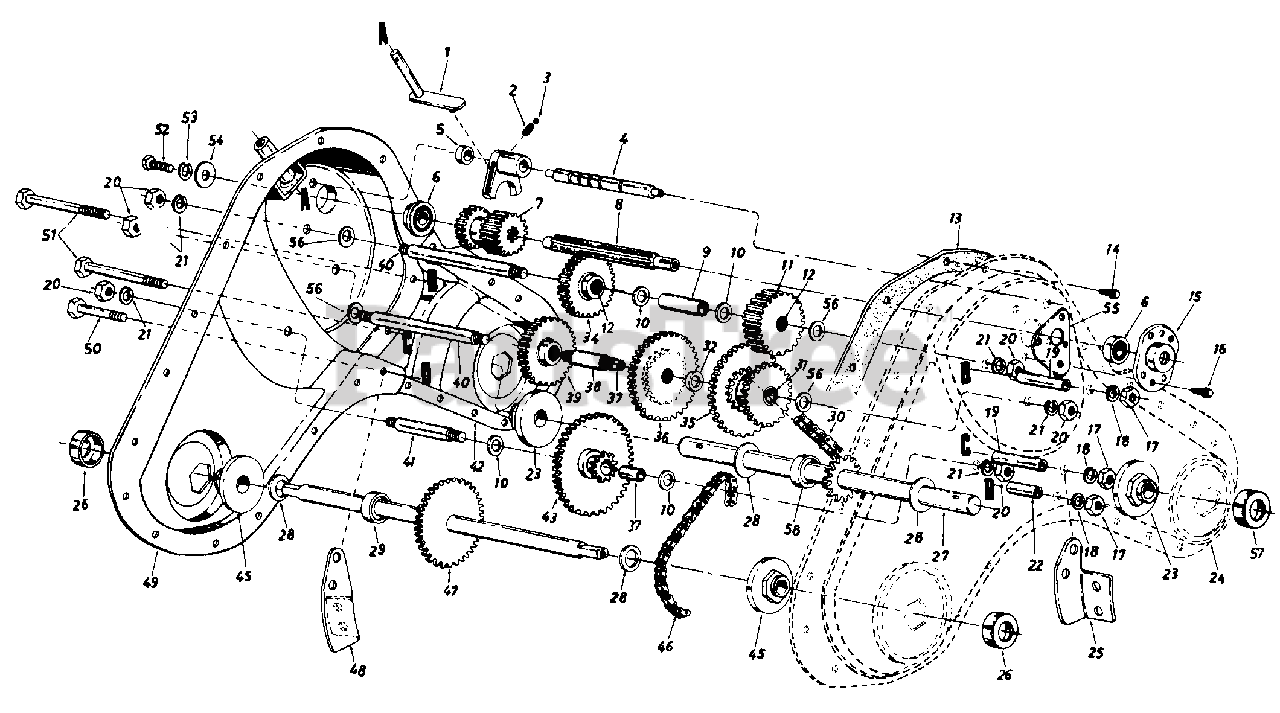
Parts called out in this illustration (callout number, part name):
1	Shifting Bracket Ass'y.
2	Compression Spring .50n Lg.
3	Ball Detent .250" Dia.
4	Detent Shaft 1/2" Dia.
5	Spacer .505" I.D. x.88" O.D.
6	Ball Brg. .62" I.D. x 1.38"
7	Spur Gear 16T
8	Input Spline Shaft 7/8
9	Spacer 657n I.D. x 2.85" Lg.
10	Fl-Wash. 640n I.D. x 1.24n
11	Spur Gear 30T 7/8" I.D. x 11/4 " O. D .
12	Needle Bearing 5/8n I.D.
13	Gasket-Trans. Hsg.
14	Hex Wash. S-Tap Scr. 1/4-20 x.50" Lg.
15	1-3/8" Dia. Bearing Housing
16	Hex TT-Tap Scr. 1/4-20 x .75"
17	Hex Nut 5/16-18 Thd.
18	L-Wash. 5/16" I.D.
19	Spacer 1.56" Lg.
20	Hex Nut 7/16-20 Thd.
21	Bell-Wash. .45" I.D. x 1.0"
22	Spacer 1.015" Lg.
23	Tine Shaft Brg. 1.002 x 2.50
24	Trans. Housing Ass'y.-L.H.
27	Tine Shaft Ass'y. 1.00" O.D.
28	Thrust Washer 1.030 I.D. x 1.62" O.D.
29	Spacer 1.0" I.D. x .50" Lg.
30	Chain #50 5/8 Pitch x 52 Links-Endless
31	Needle Bearing 518" I.D.
32	Fl-Wash. 518" I.D. x 11/4" O.D. x .150
34	Spur Gear 30T 12/16n I.D. x 1/2" W
35	30/44T Gear Ass'y. Comp.
36	Spur Gear 44T
37	Sleeve Bearing
38	Gear Hub 3/4" I.D. x 3.0" Lg.
39	Spur Gear 30T 1.0" I.D. x 1/2" W
40	Jack Shaft 518" Dia. x 5.01'
41	Jack Shaft 6/8a Dia. x 2.38"
45	Wheel Brg. .752 x 2.50
46	#420 Chain 1/2 Pitch x 50 Links-Endless
47	Wheel Shaft Ass'y. 13"
51	Hex Bolt 5/16-18 x 2.50"
52	Hex Bolt 1/4-20 x .62" Lg.
53	L-Wash. 3/8" I.D.
54	Fl-Wash. 1/4" I.D. x .93" O.D.
55	Gear Positioner Bracket
56	Fl-Wash. 7116" I.D. x 1-3/8" O.D.
57	Dust Cover Ass'y. 1.0" Shaft
58	Spacer .75" I.D. x 2.0" O.D.
